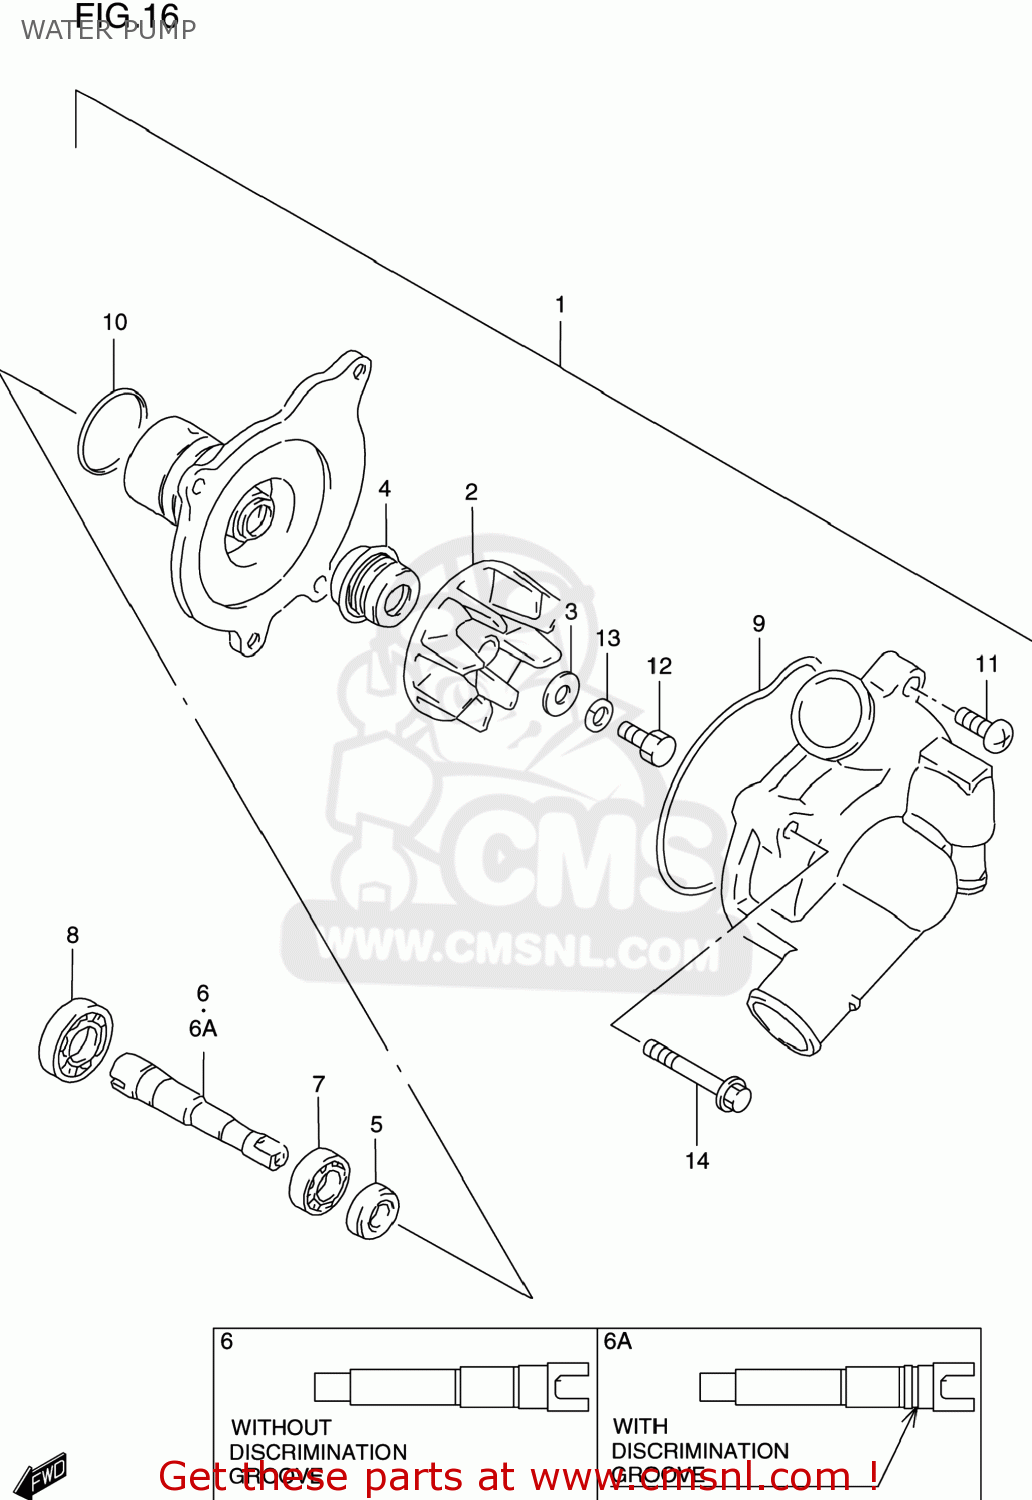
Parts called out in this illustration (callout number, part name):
1	PUMP ASSY,WATER
2	IMPELLER
3	GASKET(6X15X2.2) (NAS)
4	SEAL,MECHANICAL
5	SEAL,OIL(10X21X5)
6	SHAFT,WATER PUMP
6A	SHAFT,WATER PUMP
7	BEARING(10X26X8)
8	BEARING(12X28X8)
9	O RING
10	O RING,WATER PUMP HOLDER
11	SCREW 6X16
12	BOLT(6X13)
13	WASHER
14	BOLT
